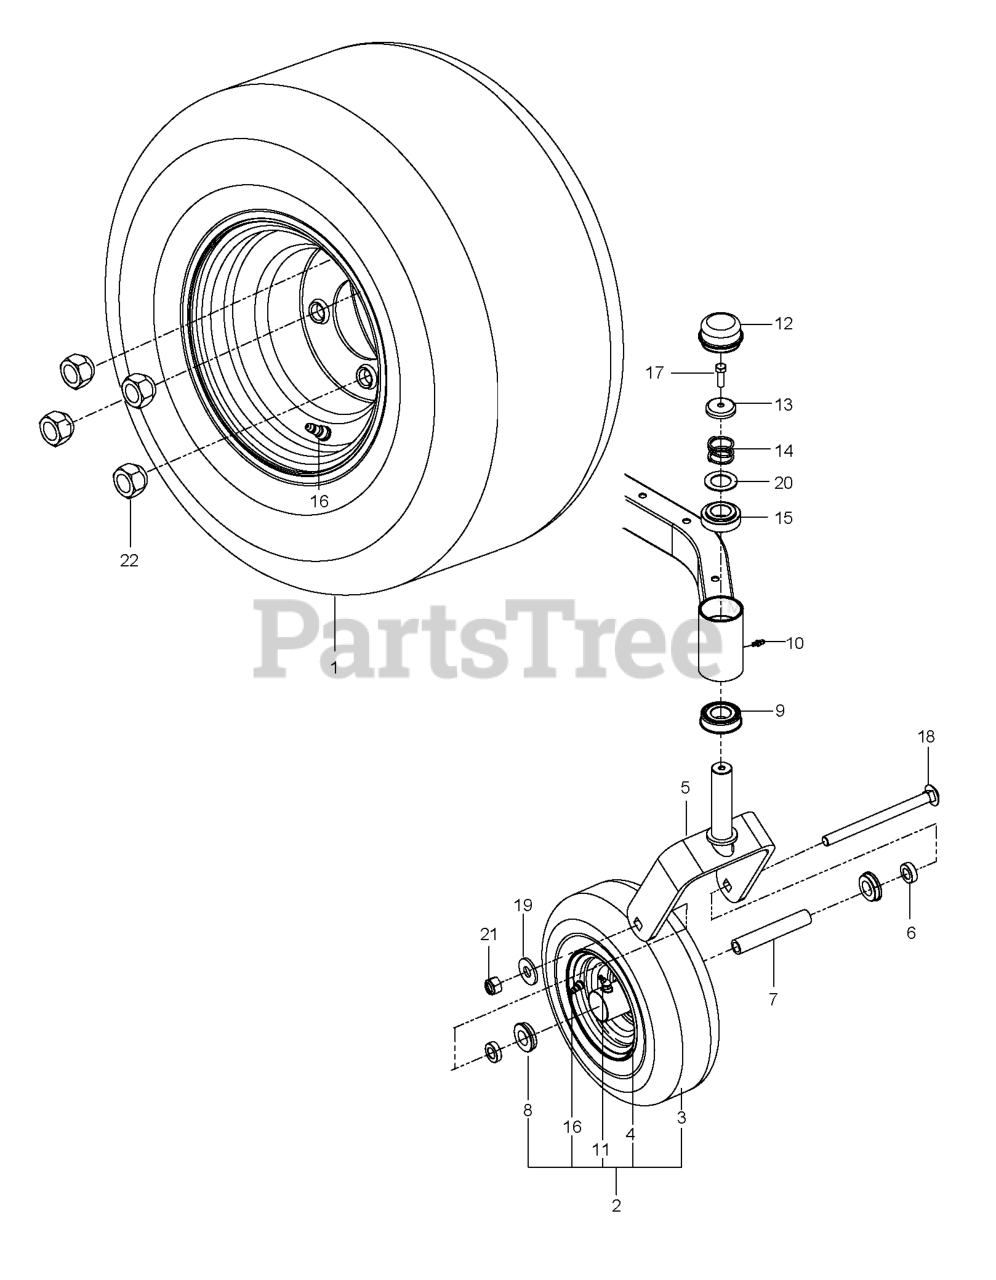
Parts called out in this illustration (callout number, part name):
1	WHEEL ASM.18X8.5-8.KENDA.
2	TIRE.CASTER.ASSEM.11X4-5.GR
3	TIRE.11"X4"-5.4PLY.SMOOTH.KEND
5	YOKE.CASTER.ORANGE
6	SPACER, 5/16"
8	BEARING RETAINER
9	BEARING FLANGED
10	ZERK
11	ZERK, 3/16, DRIVE IN
12	GREASE CAP
13	CASTER.PLUG
14	SPRING, CASTER
15	BUSHING, CASTER
16	VALVE STEM TR-412
17	5/16-18X1 HHB G5W/NY
18	RHSNB 1/2-13 X 6.50 GR2 ZD
19	WASH USS FLAT 1/2
20	WASHER, 1.025 ID X 1.64
21	NUT 1/2-13 HEX NYLOC ZD
22	LUG NUT 1/2F
